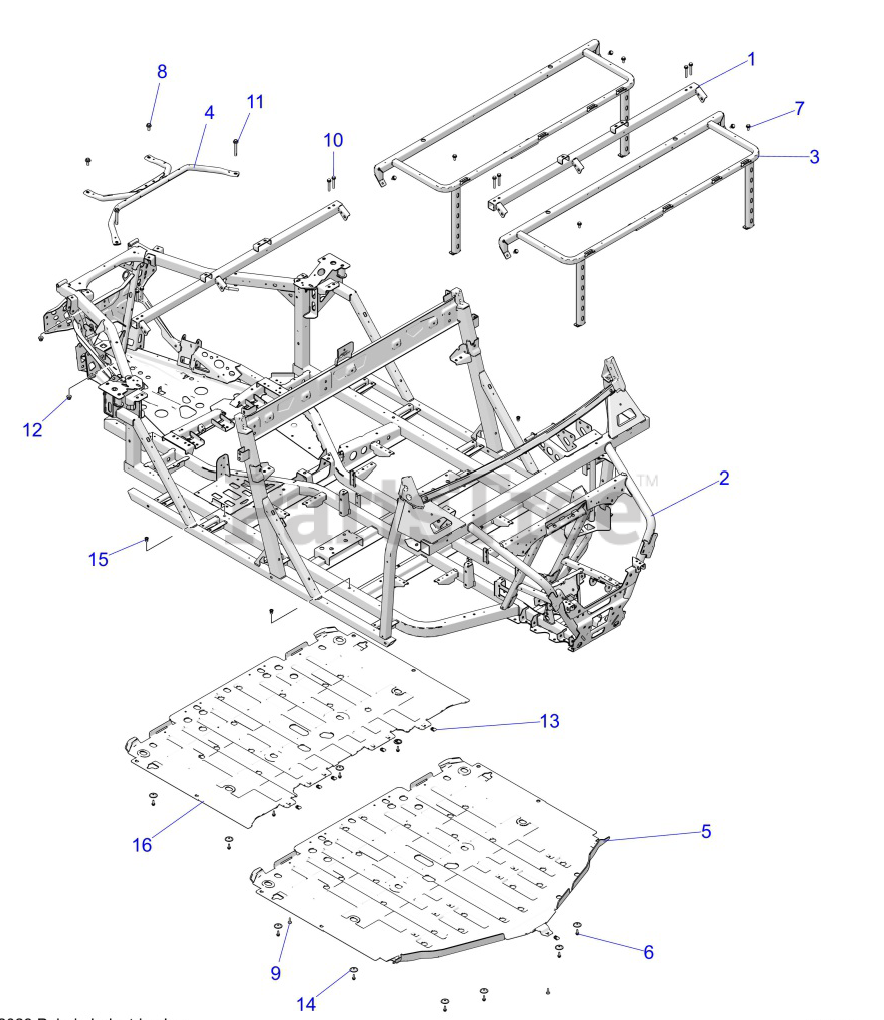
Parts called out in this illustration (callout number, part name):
1	WELD-CROSSBAR- ECOAT
2	WELD-FRAME,MAIN,CREW,M.BLK
3	WELD-SEAT BASE,MAIN,ECOAT
4	WELD-FRAME- BRACE- M-BLK
5	PLATE-SKID- BLK
6	SCR-M6X1.0X20-HXHD-FLG-TDFM-BL
7	BOLT-M8X1.25X20-HXFLG-TAP/R-OD
8	SCR-M10X1.5X25-8.8 HFS ZOD
9	SCR-TXTH-M6X1.0X25 RIE
10	SCR-HXFL-M8X1.25X55 8.8 ZB
11	SCR-HXFL-M10X1.5X75 8.8 ZY3 NY
12	NUT-M10X1.5 HFN NYLOC ZOD
13	NUT-M6-1.0- U-TYPE (2.5-3.8)
14	WASHER SKID PLATE
16	PLATE-SKID- REAR- BLK
